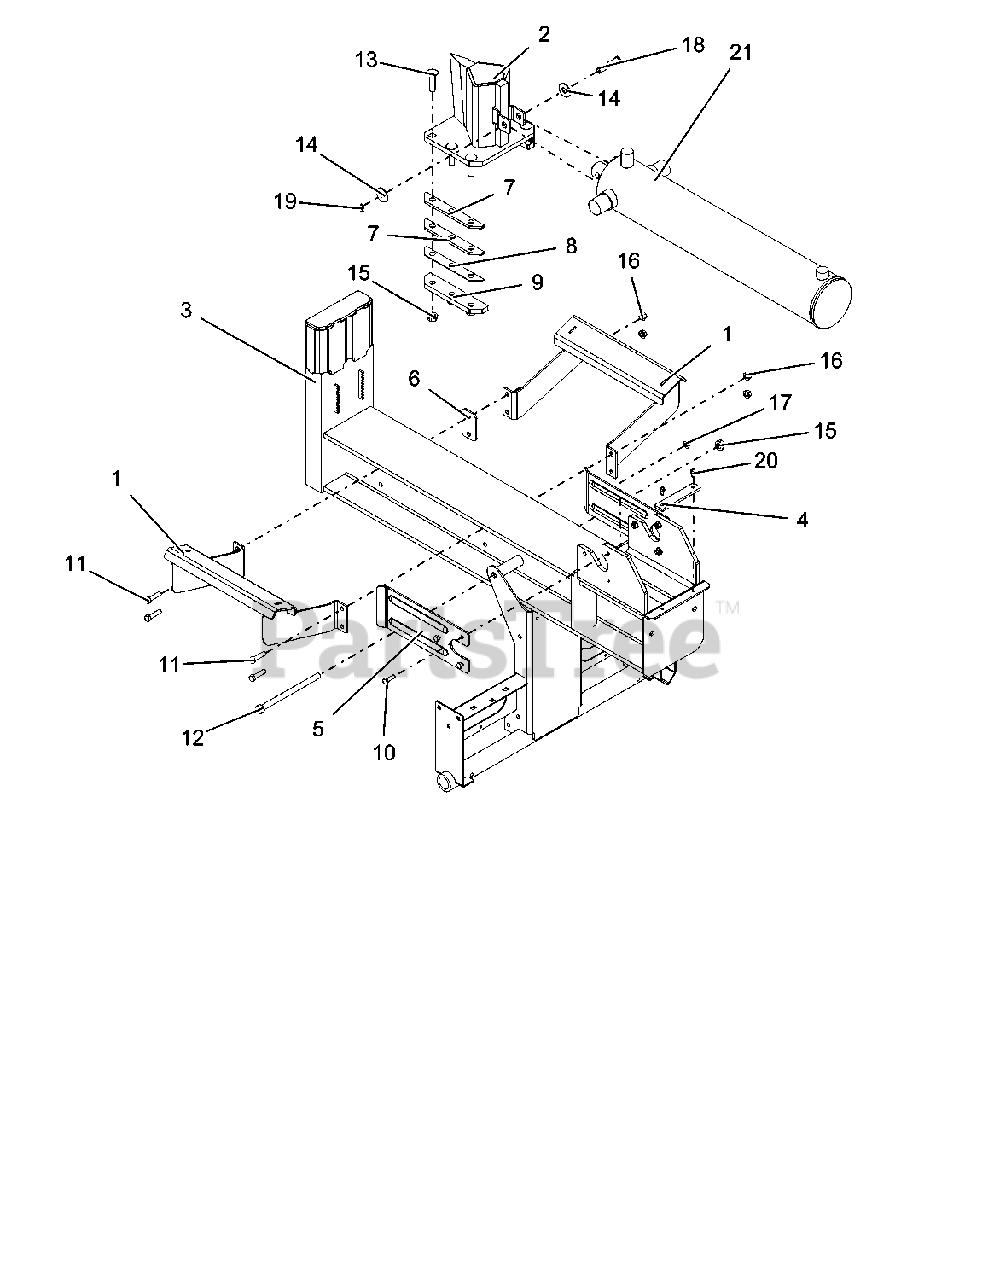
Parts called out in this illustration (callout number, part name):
1	WLDMT, LOG CRADLE
2	WLDMT, SPLITTER WEDGE
3	WLDMT, CE SPLITTER BEAM
4	SPCR, CYLINDER
5	PLATE, STRIPPER
6	PLATE, SPCR -WORK TABLE
7	SPCR, WEDGE
8	SHIM, SPLITTER WEDGE
9	RETAINER, WEDGE-BLACK
10	BLT-HEX .31-18X1.00 GR5 YWZC
11	BLT-HEX .38-16X1.50 GR5 YWZC
12	BLT-HEX .50-13X7.50 GR5 YWZC
13	BLT-RDHDSQNK .50-13X2.00 G8 Y
14	WSHR-FL-STL.563X1.38X.109YWZC
15	NUT-LK-CTR-FLG .50-13 YWZC
16	NUT, LK-TOP-FLG .38-16 YWZC
17	NUT, LK-TOP-FLG .312-18 YWZC
18	PIN-CLEV .494X2.50X2.27 YWZC
19	CLIP, SPRING
20	SCR-TAP .25-20X.50 HWH TR YWZ
21	CYLINDER, SPLITTER - 4.5"
